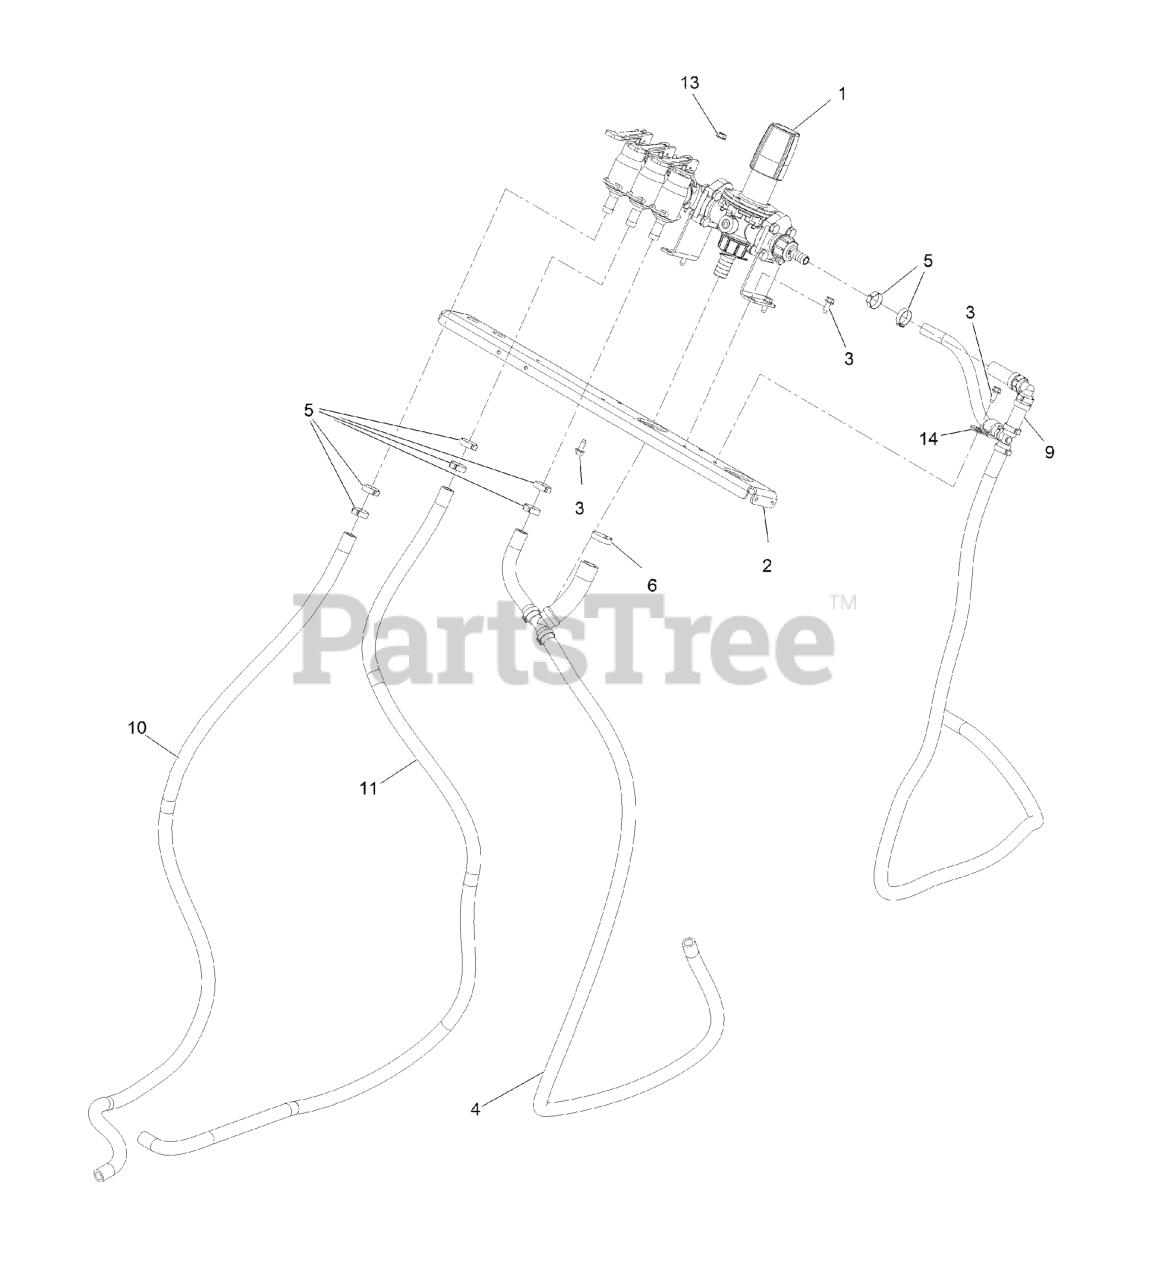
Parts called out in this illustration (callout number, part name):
1	SPRAY MANIFOLD ASSEMBLY
2	CROSSMEMBER-COLUMN
3	SCREW-HWH
4	HOSE ASM
9	HOSE ASM
10	HOSE-WATER
11	HOSE-WATER
14	CLIP-LOOM
